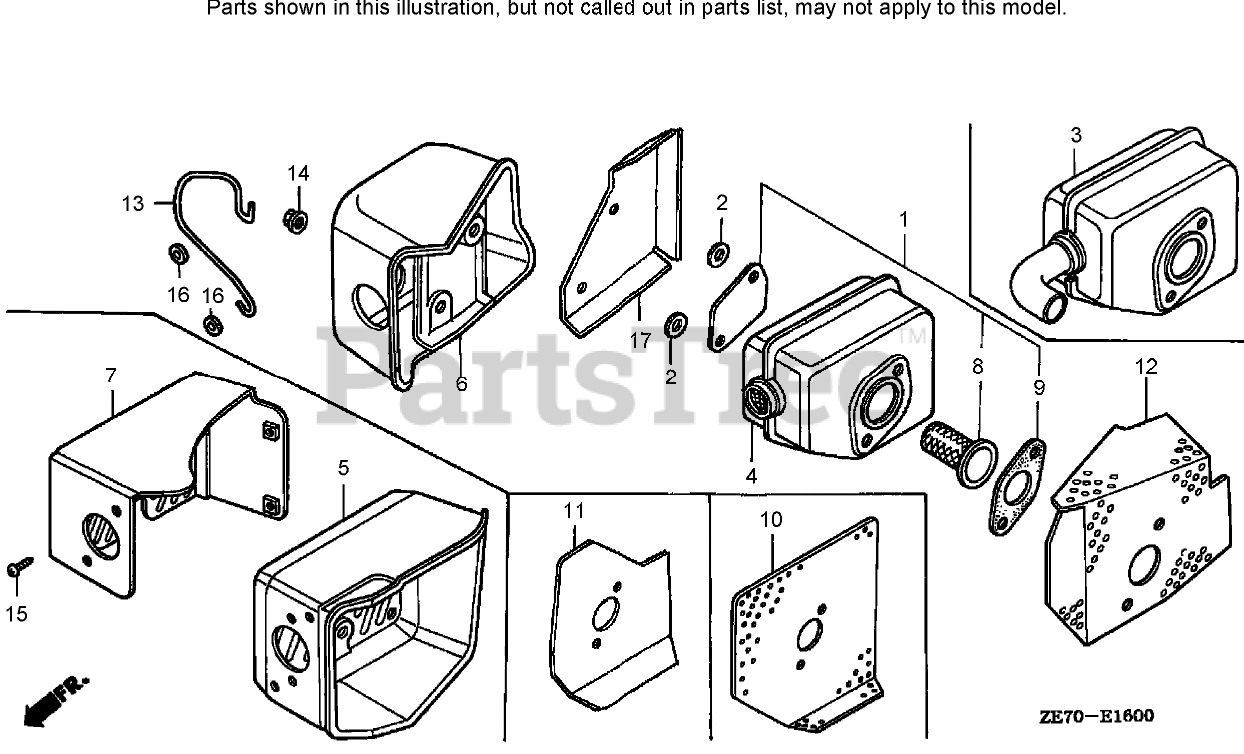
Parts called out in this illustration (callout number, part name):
1	SPARK ARRESTER KIT
4	Muffler
6	Protector-Muffler
8	SPARK ARRESTER KIT
9	Gasket-Muffler
12	Gasket-Muffler
14	NUT-LOCK, SELF (6 mm)
